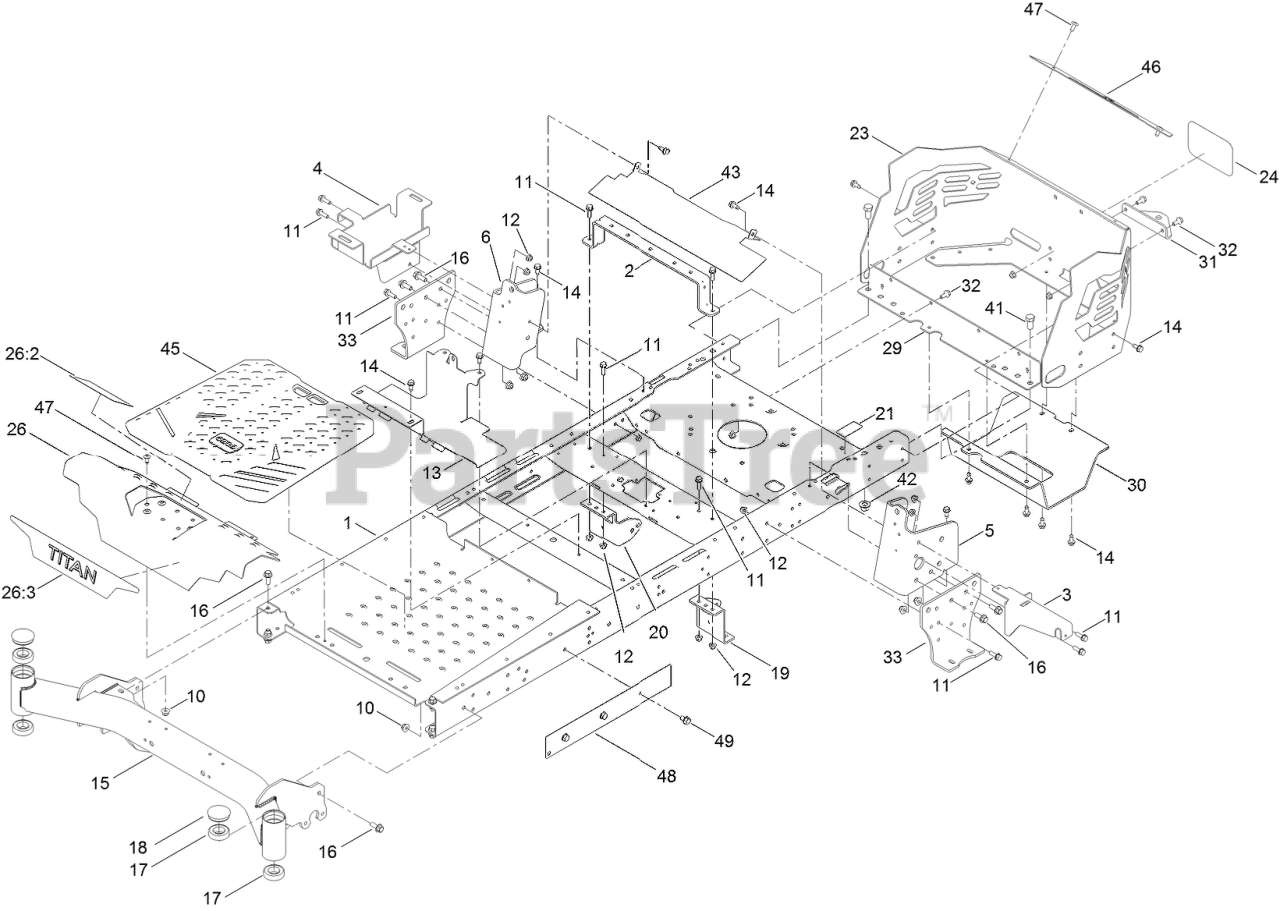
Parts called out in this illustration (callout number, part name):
1	FRAME ASM
2	BRACE-SEAT, REAR (WIDE)
3	BRACKET-SUPPORT, POD (LH)
4	TRAY-BATTERY
5	BRACKET-MOUNTING, LH
6	BRACKET-MOUNTING, RH
10	NUT-HF, NI
11	SCREW-HHF
12	NUT-HF, NI
13	BRACKET-MOUNT
14	SCREW-HWHTF
15	FRONT AXLE ASM
16	SCREW-HHF
17	BEARING-BALL
18	CAP-GREASE
19	MOUNT-HYDRO, FRONT (LEFT)
20	MOUNT-HYDRO, FRONT (RIGHT)
21	DECAL-BYPASS
23	GUARD-ENGINE
24	DECAL
26	FOOTREST-TITAN
26:2	DECAL-DANGER
26:3	DECAL-TITAN
29	CROSSMEMBER-REAR, WIDE
30	GUARD-MUFFLER
31	BRACKET-HITCH
32	SCREW-HHF
33	MOUNT-HYDRO
41	SCREW-HH
42	NUT-LOCK
45	FLOOR MAT
46	TRIM-GUARD, ENGINE
48	PLATE-FRAME
49	SCREW-HWHTF
